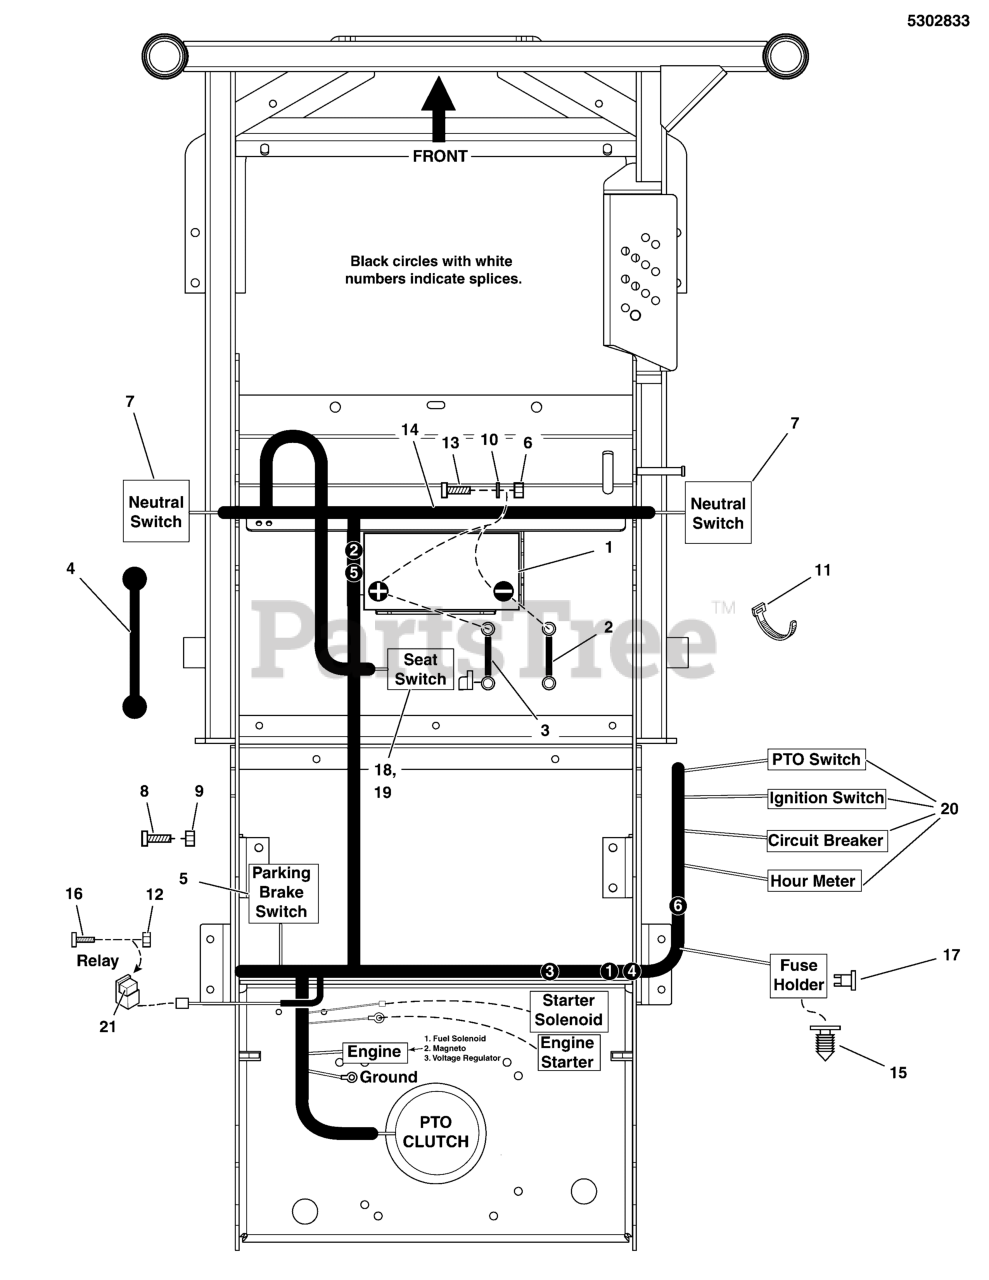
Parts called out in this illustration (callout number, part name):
2	CABLE, BATTERY, NEG, 30, 1/4-5/16
3	BATTERY CABLE, POS, 35, 1/4-5/16
4	STRAP-BLACK RUBB
5	SWITCH, PLUNGER, N.O./N.C.
6	NUT, 1/4-20 HEX SERR. FLANGE
7	SWITCH, LOW PROF, NC/NO
8	SCREW- #10-24 X 1/2 ROUND PHILLIPS
9	NUT, #10-24 HEX
10	WASHER, 1/4 SAE
11	TIE, SELF-LOCKING, 12"
12	NUT, #10-24 HEX NYLON LOCK
13	HHCS, 1/4-20 X 0.625, GR5, ZINC/CLEAR
14	WIRE HARNESS, KAWI FX, S50XT
15	FIR TREE MOUNT, PACKARD
16	SCREW, #10-24 X 3/4 ROUND PHILLIPS
17	FUSE, ATO-15 (15 AMP)(SV)
18	SWITCH, NC, W/ BOLT-IN BASE
19	SWITCH, NC, W/ TWIST-IN BASE
20	SEE INSTRUMENT CONTROL PANEL GROUP
21	RELAY, 12V, 40A (SV)
